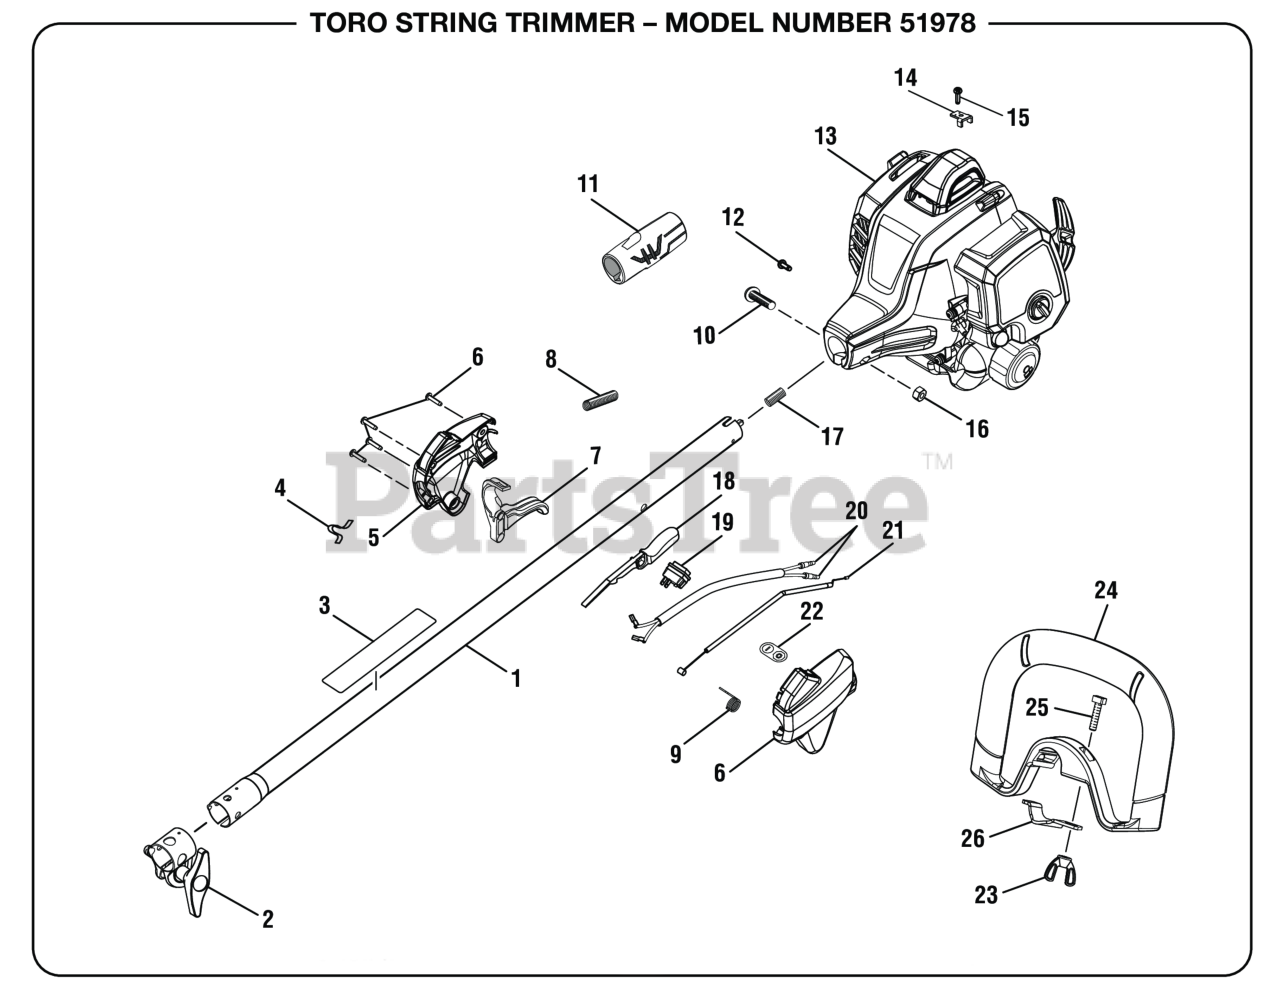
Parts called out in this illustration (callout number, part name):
1	Upper Boom Assembly
2	Boom Clamp Assembly
3	Warning Icon Label
4	Shoulder Strap Hook
5	Control Handle Assembly
6	Screw (M4 x 20 mm, T20 Torx Pan Hd. S.T.)
8	Corrugated Tube (225 mm)
9	Torsion Spring (Throttle Trigger)
10	Screw (M6 x 30 mm, T27 Torx Button Hd.)
11	Rear Handle Grip
12	Screw (M4 x 8 mm, T25 Torx Pan Hd. T.F.)
13	Power Head Assembly
14	THROTTLE CABLE CLAMP
15	Screw (M4 x 16 mm, T20 Torx Pan Hd. S.T.)
16	Hex Nut (M6.3 x 1)
17	COMPRESSION SPRING
18	Trigger Lock
19	On/Stop Switch
20	Lead Assembly
21	Throttle Cable
22	On/Stop Label
23	Wing Nut (1/4-20, Plastic)
24	Front Handle w/Grip
25	Bolt (1/4-20 x 1 in., Square Hd.)
26	Front Handle Clamp
